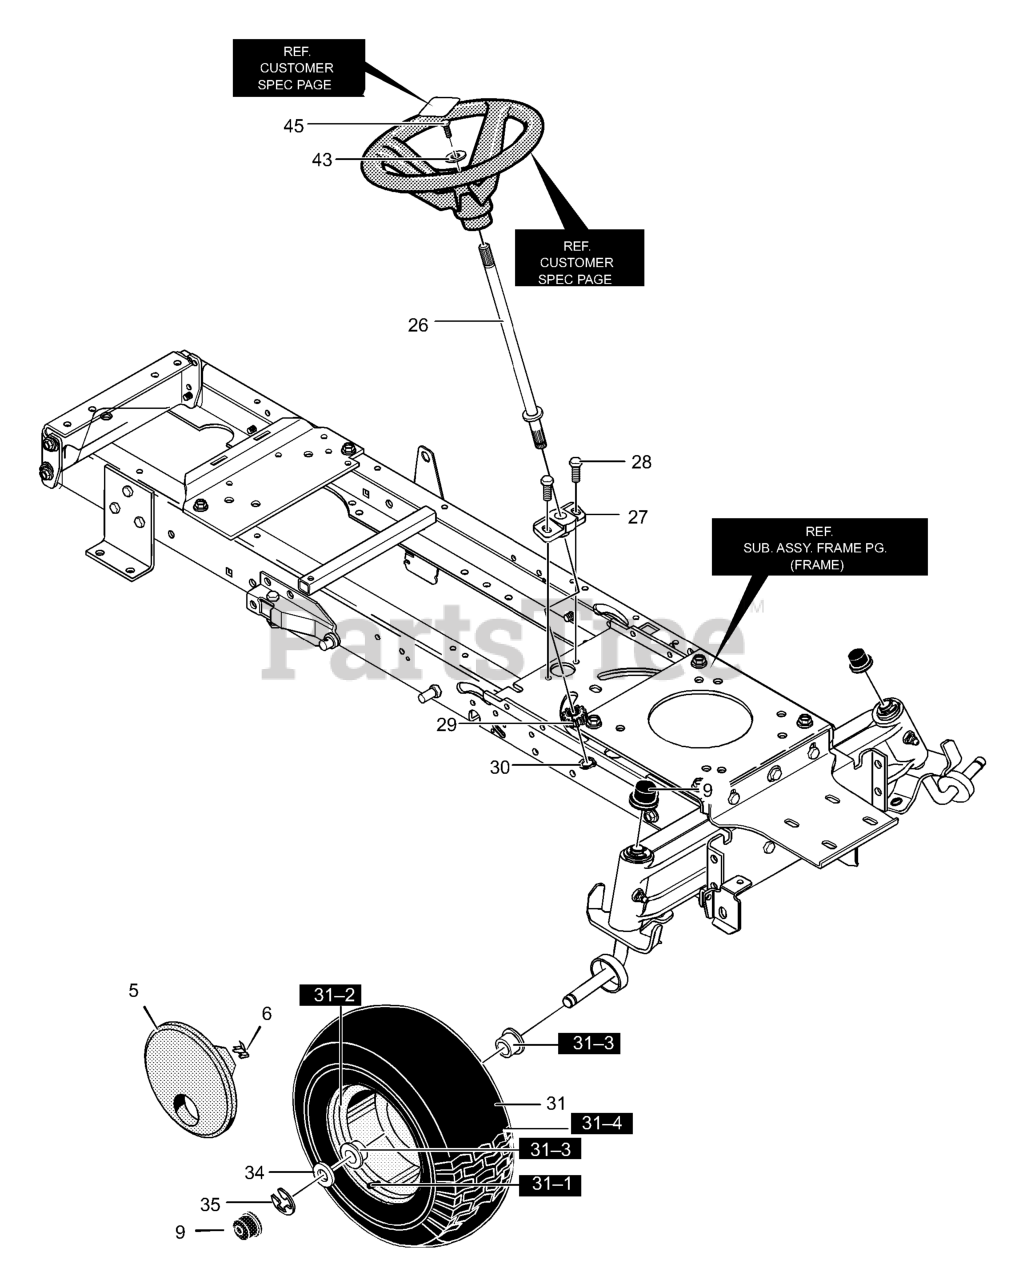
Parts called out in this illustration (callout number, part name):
5	HUB CAP, 6"
6	RETAINER
9	DUST HUB CAP
26	SHAFT, STEERING
27	BEARING-LOWER
28	SCREW, 5/16-18 x 0.75
29	GEAR, PINION
30	RETAINING RING
31	TIRE & RIM
31-1	VALVE STEM
31-3	BEARING
34	FLATWASHER
43	FLAT WASHER
45	SCREW 1/4-20X.75
